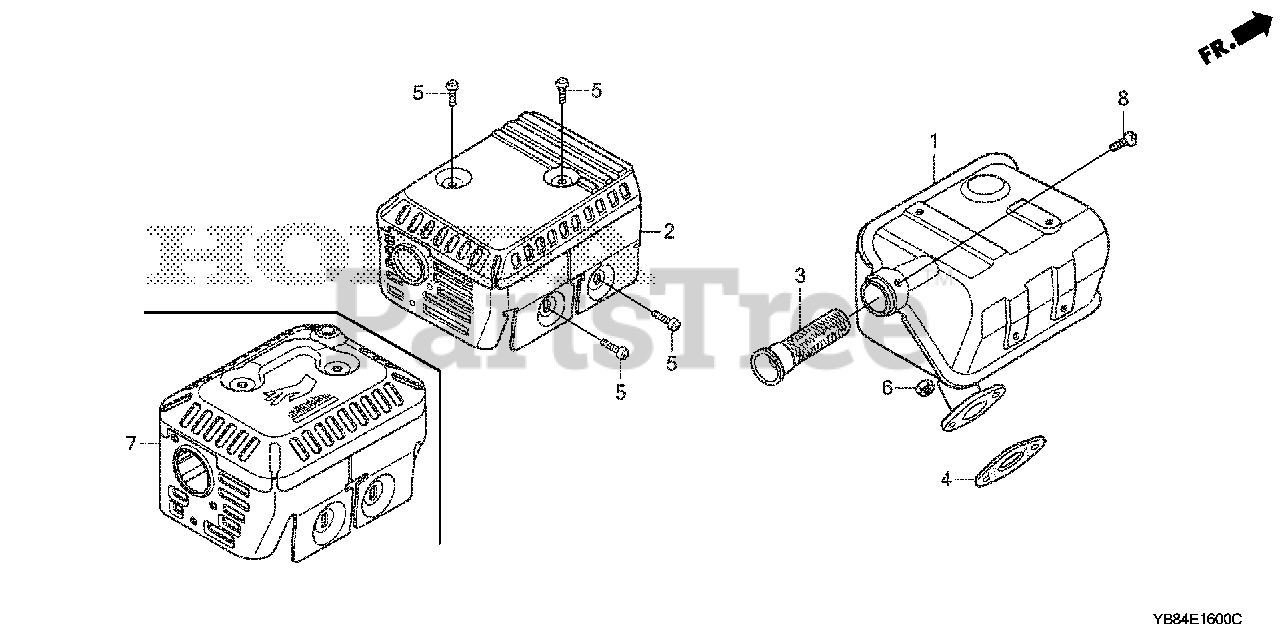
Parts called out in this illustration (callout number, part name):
1	MUFFLER (STD)
2	PROTECTOR, MUFFLER (ALUMINIZED)
4	GASKET, MUFFLER
5	SCREW, TAPPING (5X8)
6	NUT, HEX. (8MM)
